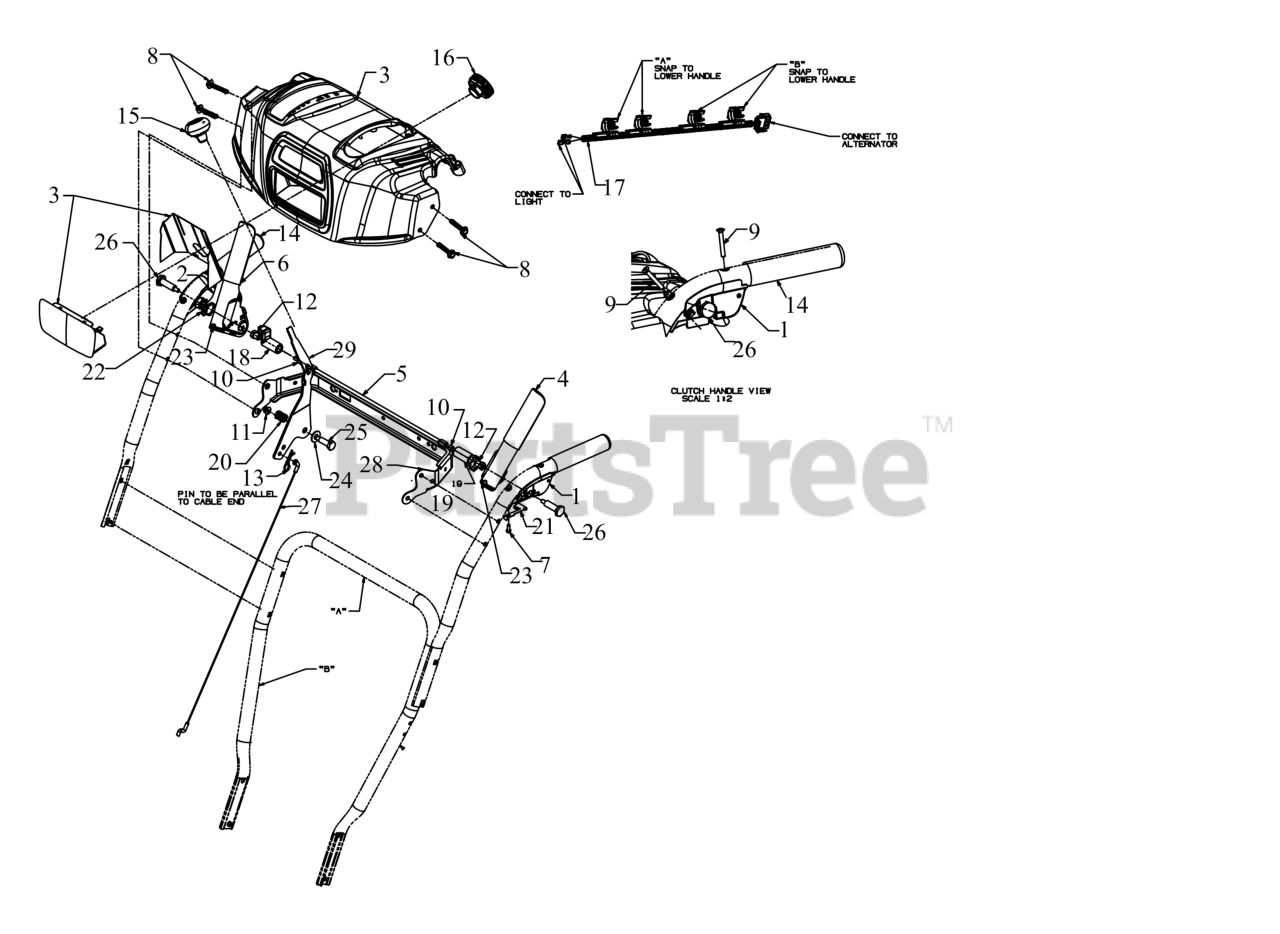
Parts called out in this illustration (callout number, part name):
1	CLUTCH LOCK HANDLE ASSEMBLY (LH)
2	CLUTCH LOCK HANDLE ASSEMBLY (RH)
3	HANDLE PANEL ASSEMBLY
4	HANDLE ASSEMBLY (LH)
5	PIVOT ROD
6	HANDLE ASSEMBLY (RH)
7	SCREW #8-16 x .50
8	SCREW 1/4-20 x 1.625
9	SCREW #10-24 x 1.375
10	SCREW 1/4-20 x .50
11	FLANGE LOCK NUT
12	HEX NUT W/PATCH
13	INTERNAL COTTER PIN
15	SHIFT KNOB
16	HEADLIGHT ASSEMBLY
17	LIGHT HARNESS
18	LOCK PLATE
19	CLUTCH LOCK CAM
20	COMPRESSION SPRING
21	CLUTCH SPRING
22	TORSION SPRING
23	RUBBER BUMPER
24	FLAT WASHER
25	SHOULDER SCREW
26	SHOULDER SCREW .437 x 1.345 1/4-20
27	SPEED SELECTOR CABLE (PLASTIC)
29	SHIFT LEVER
